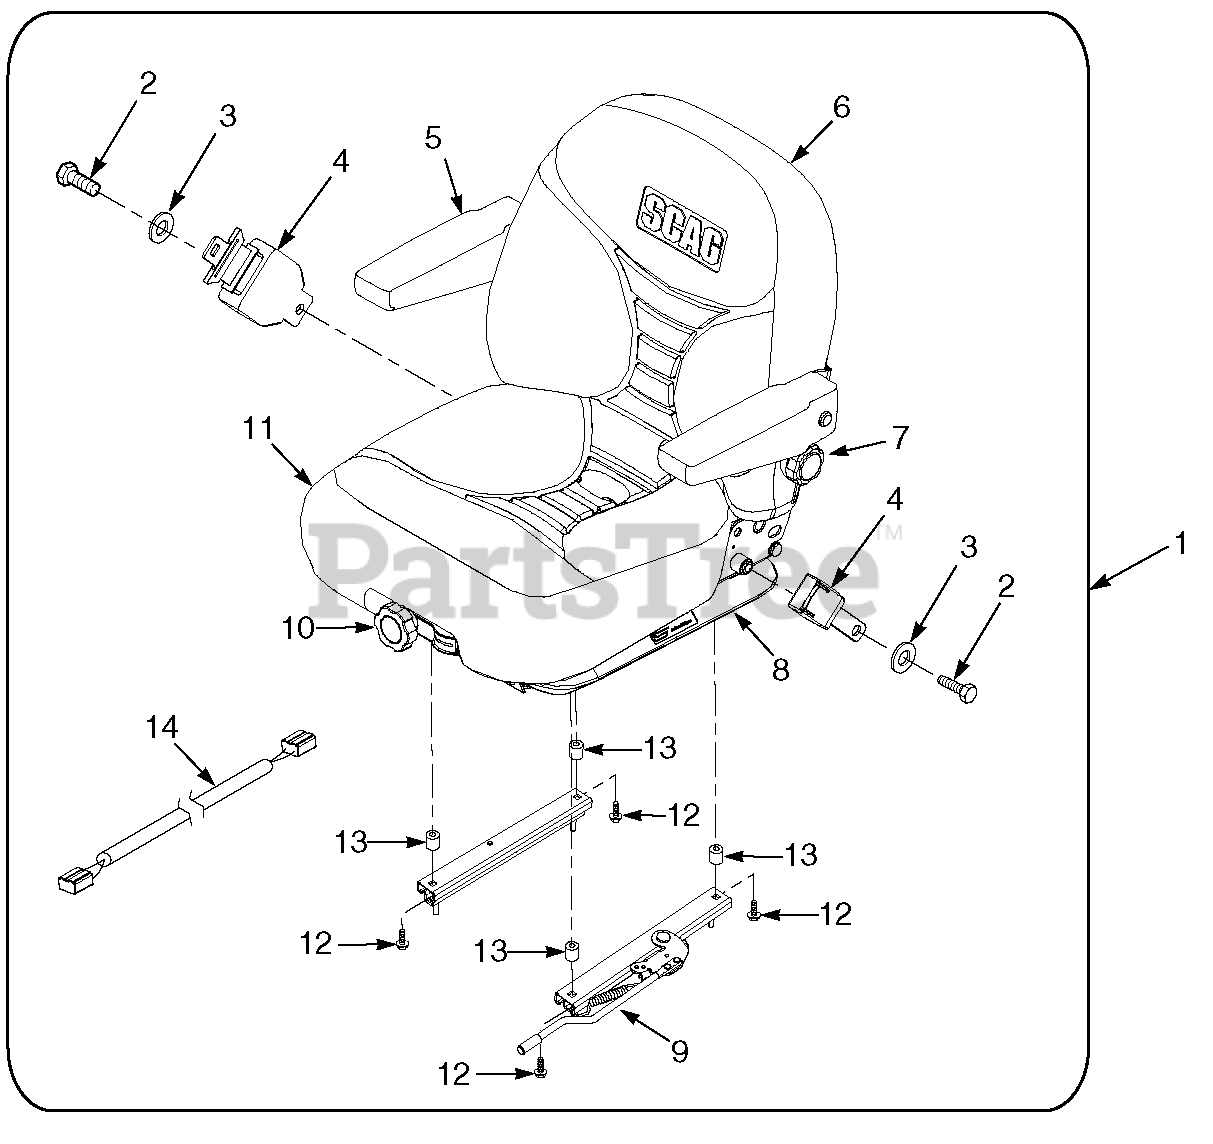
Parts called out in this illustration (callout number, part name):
1	Suspension Seat Assembly w/seat belt
2	Bolt, Hex Head 7/16-20 x 1"
3	Flatwasher, 7/16-.500 x 1.25 x .083
4	Retractable Seat Belt
5	Armrest Only
6	Back Cushion Kit
7	Lumbar Kit
8	Shock Absorber Kit
9	Seat Adjustment, Track Set
10	Weight Adjustment Kit
11	Seat Cushion Kit Seat Drain Kit
12	Bolt, Hex Head 5/16-18 x 1-3/4"
13	Spacer
14	Wire Harness Adapter
